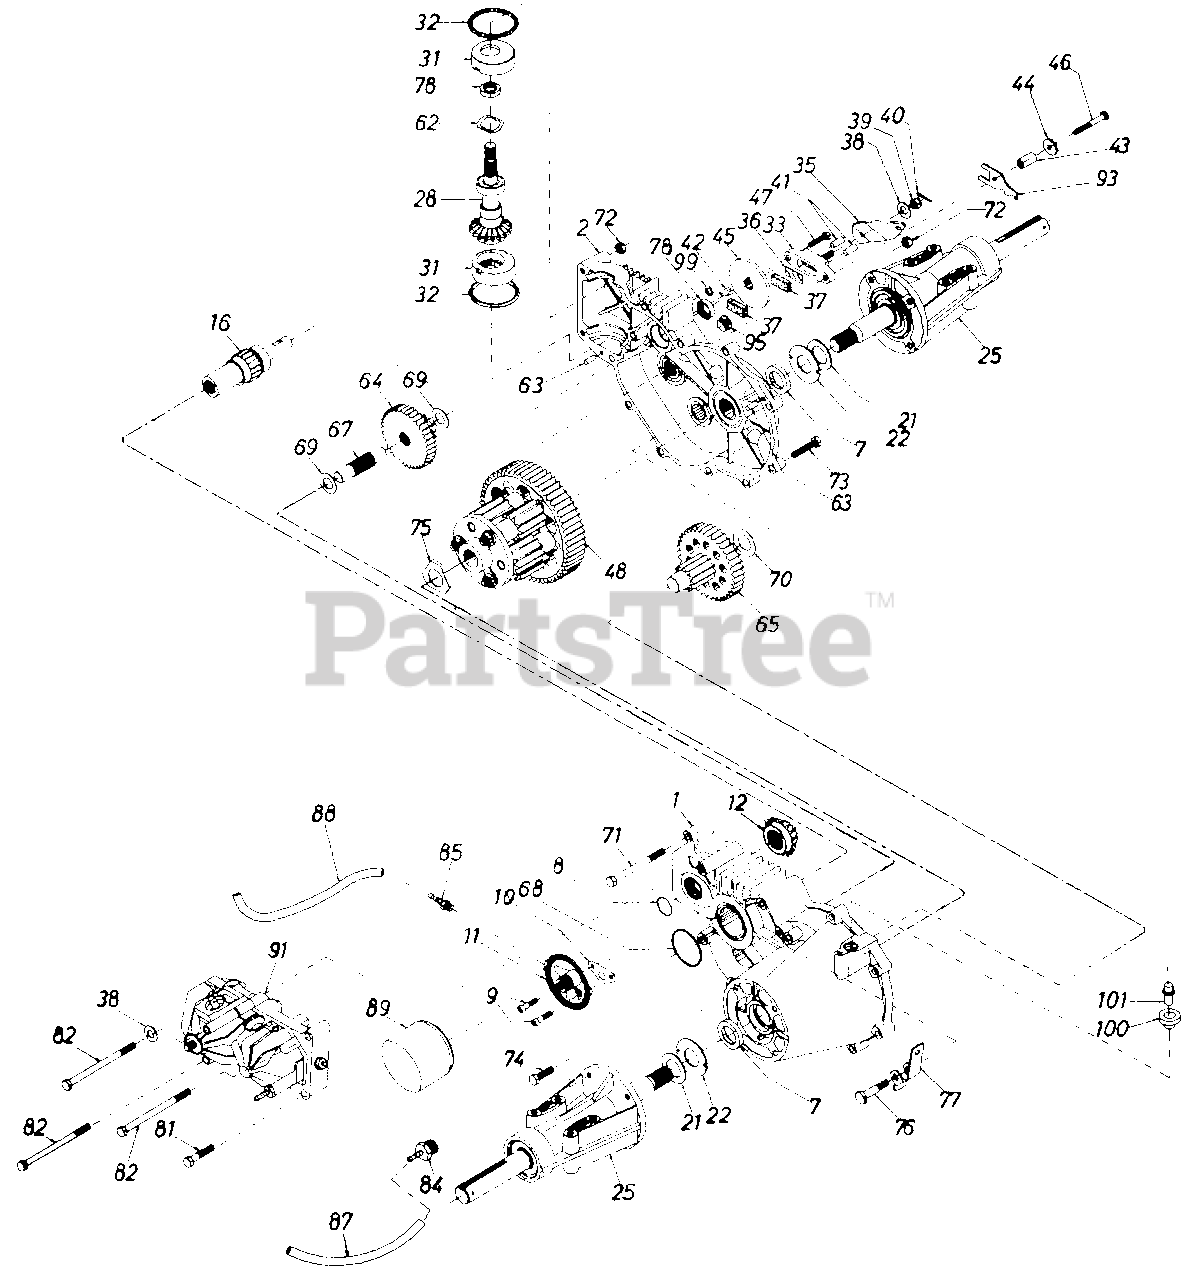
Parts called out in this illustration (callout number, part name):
1	Housing - L.H. Ass'y.
2	Housing - R.H. Ass'y.
7	Oil Seal .984" x 1.5" x .25"
8	Quad Ring
10	Filter Base Gasket
11	Filter Base Ass'y.
12	Pinion Ass'y.
16	Brake Shaft Ass'y.
21	Washer, 1.0" x 1.63" x .08"
22	Washer, 1.0 x 2.06" x .09"
25	Axle Mounting Horn Ass'y.
28	Input Ass'y.
31	Ret. Bearing
32	O-Ring 2-1/2" O.D.
33	(Sub) Brake Yoke Ass'y.
35	Brake Arm
36	Puck Plate
37	Brake Puck
38	Washer, 7/16" x 7/8" O.D. x .060 H.T.
39	Nut, Castle 5/16-24 PL
40	Cotter Pin
41	Brake Actuating Pin
42	Hi-Pro Key 3/16" x 5/8"
43	Torsion Spring Spacer
44	Washer 7/8 O.D. x .260 I.D. x 1/8
45	Disc Brake
46	Bolt 1/4-20" x 2 W/Nylok Gr. 5
47	Bolt 1/4-20" x 1 W/Nylok Gr. 5
48	Differential Ass'y.
62	Wave Washer
63	Dowel Pin
64	Reduction Gear 14T-38T
65	Final Drive Pinion Ass'y.
67	Jack Shaft
68	O-Ring
69	Fl-Wash. 5/8" I.D. x 1-5/32" O.D. Ht.
70	Fl-Wash. 7/8" I.D. x 1-1/2" O.D. Ht.
71	Hex Bolt H.D. 5/16-18" x 3-1/2"
72	Hex Lock Nut 5/16-18" 2-Way Plt.
73	Hex Bolt 5/16-18" x 1-1/2" Gr. 5 Plt.
74	Hex Bolt 5/16-18" x 1
75	Differential Washer .050
76	Shld. Bolt
77	Freewheel Actuating Arm
78	Oil Seal .625" x 1.0" x .25"
81	Hex Bolt 5/16-18" x 1-3/4"
82	Hex Bolt 5/16-18" x 4-1/2"
84	SAE Port Straight Fitting 7/8"
85	SAE Port Straight Fitting 7/16"
87	Hose, 8-1/2" Long
88	Hose 10-1/2" Long
89	Spin-On Filter
91	Transmission
93	Bracket
95	Straight Thread Plug
99	Washer 5/16" I.D. x 9/16" O.D.
100	Vent Bushing
